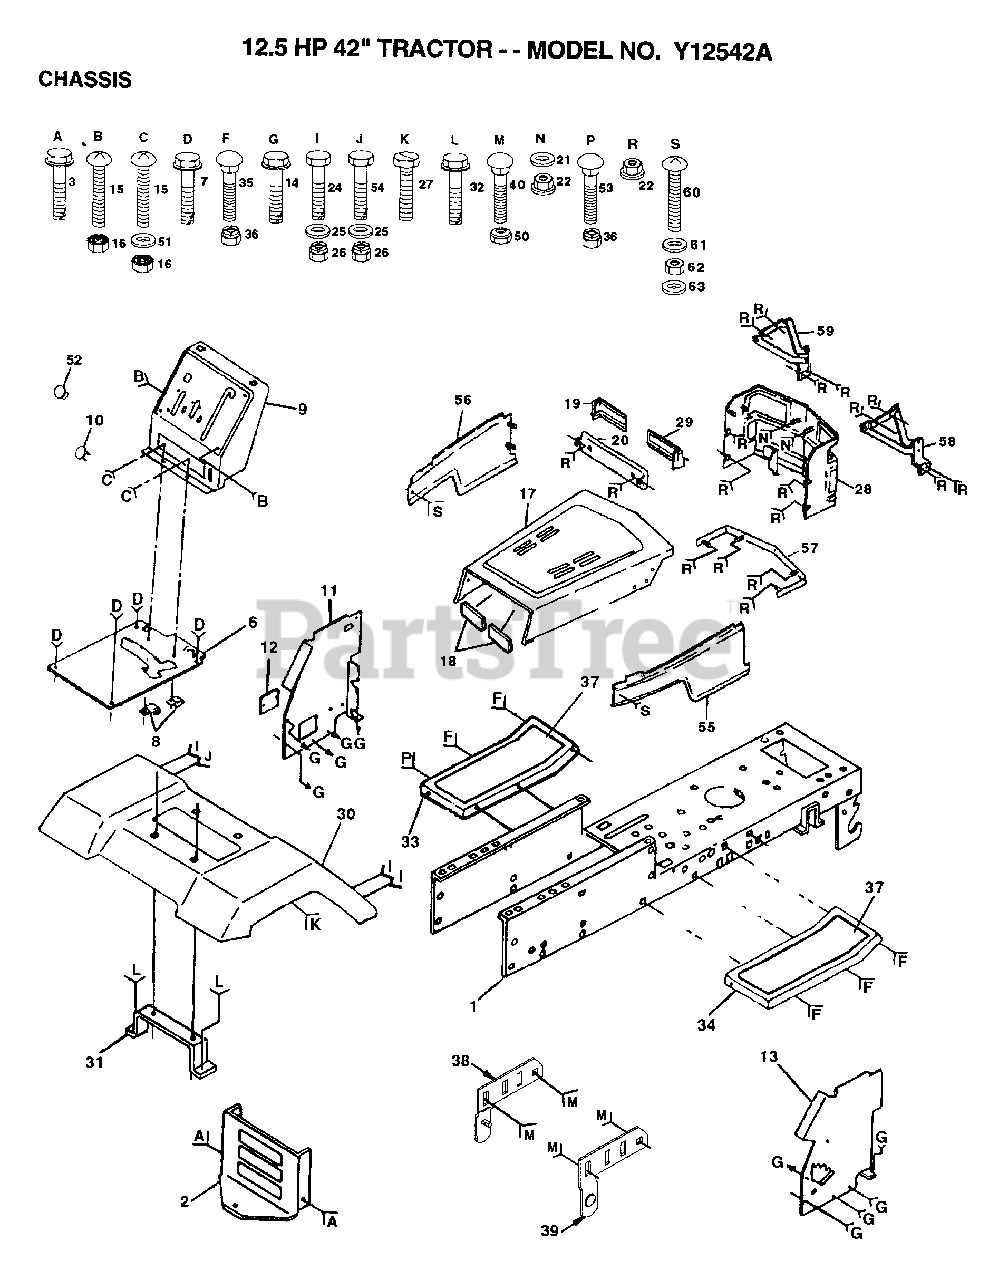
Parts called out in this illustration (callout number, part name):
3	SCREW
7	SCREW LT
8	CLIP T
10	PLUG BUTTON T
11	PANEL DASH LH
12	COVER ACCESS
14	SCREW LT
15	SCREW
16	NUT.LOCK.5/16-24
21	WASHER PM
22	PAL NUT LT
25	WASHER
27	SCREW LT
31	BRKT FENDER
32	SCREW
35	BOLT
37	FOOTREST PAD
38	PIVOT BRKT LH
39	PIVOT BRKT RH
50	NUT
51	WASHER
52	PLUG DOME
55	SIDE PANEL ASM RH
56	SIDE PANEL ASM LH
57	STRAP ASM GRILL
58	"HINGE,HOOD,RH T"
59	"HINGE,HOOD,LH T"
60	"SCREW,SPECIAL"
62	RETAINER
63	"GROMMET,PLASTIC"
